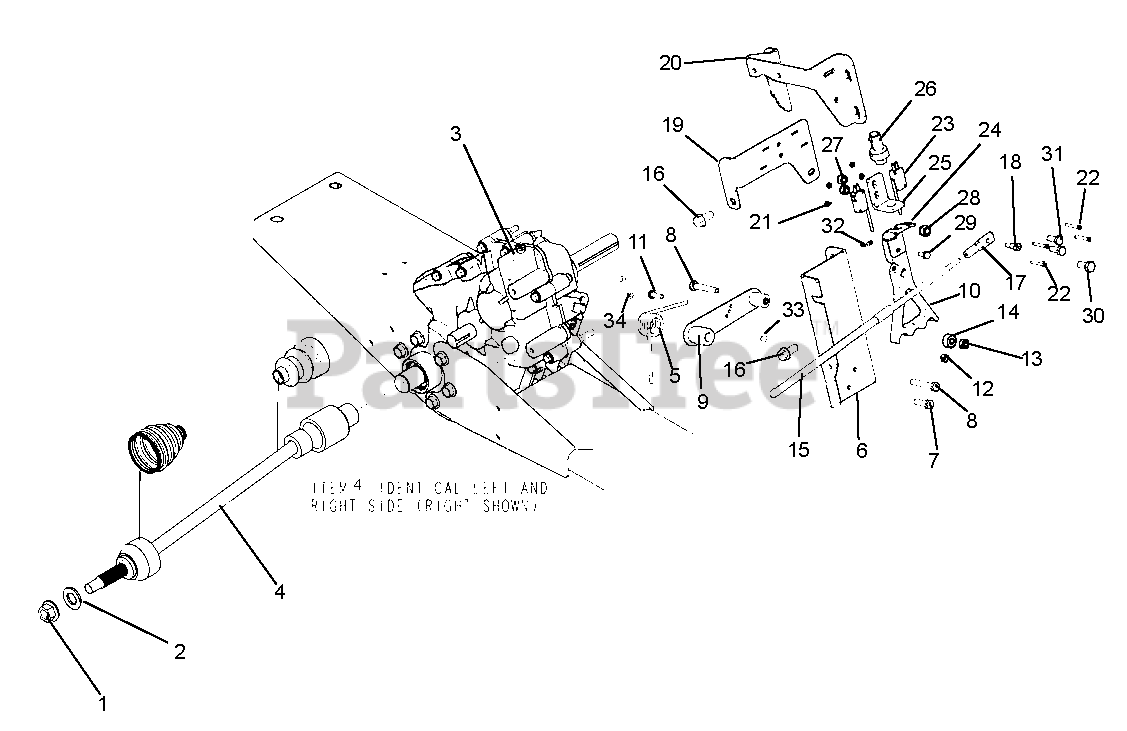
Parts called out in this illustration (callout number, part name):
1	NUT, HEX M16 X 1.5 TOP LOCK PLT
2	WASHER, FLAT STEEL .812 X 1.50 X .135 YWZC
3	TRANSAXLE WITH AUTO-LOCK DIFF.
4	REAR AXLE SHFT ST, 24T INT.SPL
5	SPRING, TORSION, 1.058 X .777
6	BRACKET, SHIFT
7	BOLT, HEX .25-20 X 1.00 GR5 YWZC
8	BOLT, HEX .25-20 X 1.75 GR5 YWZC
9	FOLLOWER WLDT
10	SHIFT CAM, TRANS SIDE
11	SCREW, MCH 10-24 X .75 HWH YWZC
12	LOCKNUT, 10-24 CENTER
13	NUT, LOCKING CENTER .25-20 YWZC
14	BEARING, BALL .250 X .688 X .313
15	SHIFT CABLE (DASH)
16	HFS 5/16-18 X 3/4 GR5
17	CABLE END
18	BOLT, SHOULDER .25 X .375
19	BRACKET, MNT, SWITCH
20	BRACKET, CVT COVER TO TRANS.
21	NUT, HEX 4-40 YWZC GR5
22	HSHCS #4-40 X 1
23	PARK BRAKE MICRO-SWITCH
24	BRACKET, SWITCH ACTIVATING
25	MOUNT, PLUNGER SWITCH
26	SWITCH, NEUTRAL
27	NUT, LOCKING NYLON .250-20 YWZC
28	NUT, LOCKING NYLON .312-18 YWZC
29	SCREW, MCH 10-24 X .50 HWH YWZC
30	BOLT, HEX .31-18 X .75 GR5 YWZC
31	BOLT, HEX .25-20 X .75 GR5 YWZC
32	SCREW, SET .25-28 X .375 SK CUP
33	BUSHING, 0253 X .495 X 1.0625
34	NUT, LOCKING CENTER .25-20 YWZC
